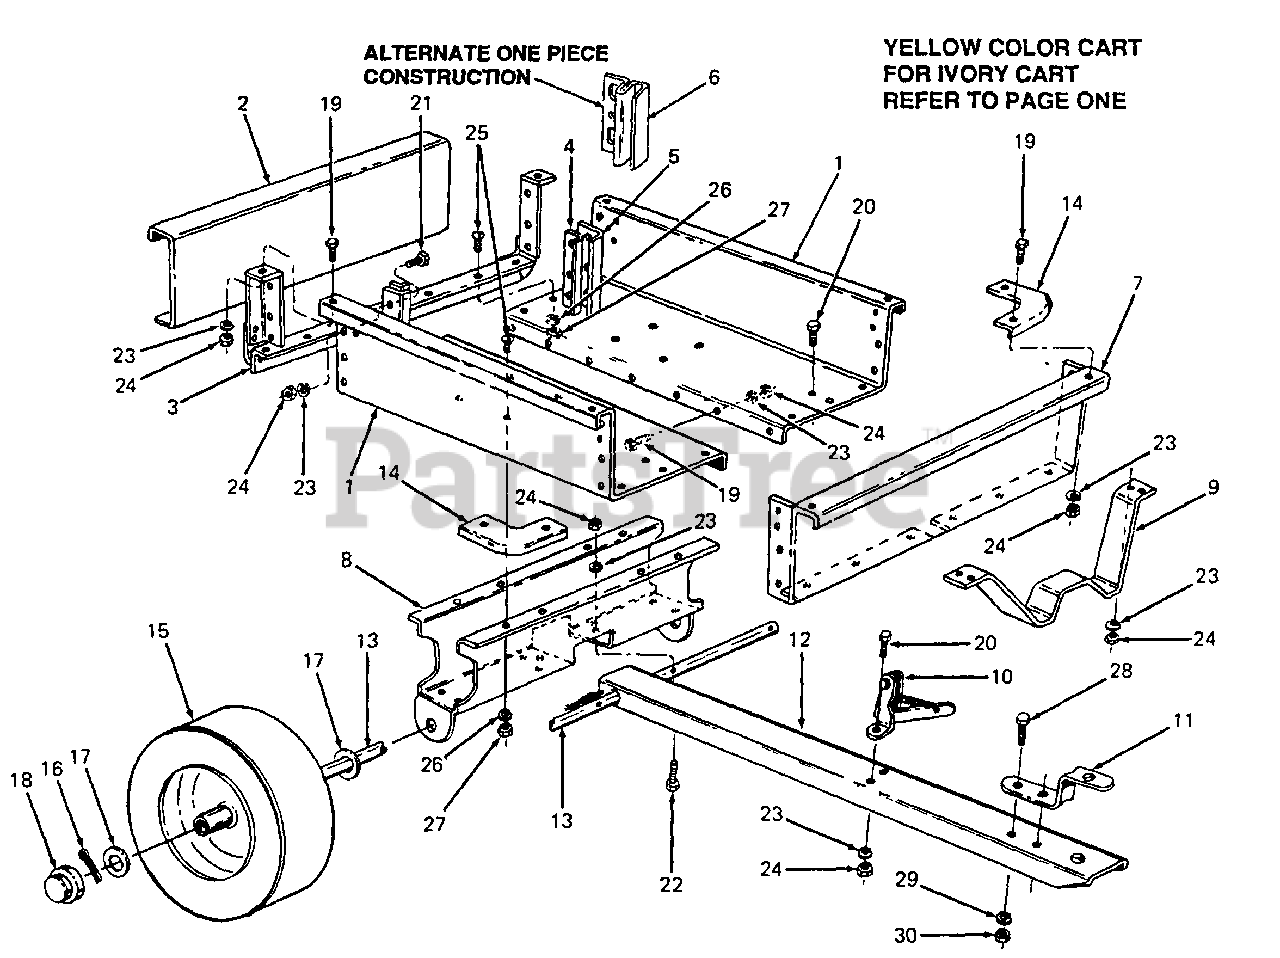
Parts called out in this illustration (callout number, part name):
5	Guide, Tailgate - Outside
6	Guide, Tailgate - One Piece
17	Washer, Flat, 1.03 ID
18	Hub Cap
19	Screw, Hex Cap, 1/4-20 X .50 Lg
20	Screw, Hex Cap, 1/4-20 X .62 Lg
21	Screw, Hex Cap, 1/4-20 X .75 Lg
22	Screw, Hex Cap, 1/4-20 X 1.75 Lg
23	Washer, Lock, 1/4
24	Nut, Hex, 1/4-20
25	Screw, Truss Hd, 5/16-18 X .75 Lg
26	Washer, Lock, 5/16
27	Nut, Hex, 5/16-18
28	Screw, Hex Cap, 3/8-16 X 1.0 Lg GR5
29	Washer, Lock, 3/8
30	Nut, Hex, 3/8-16
